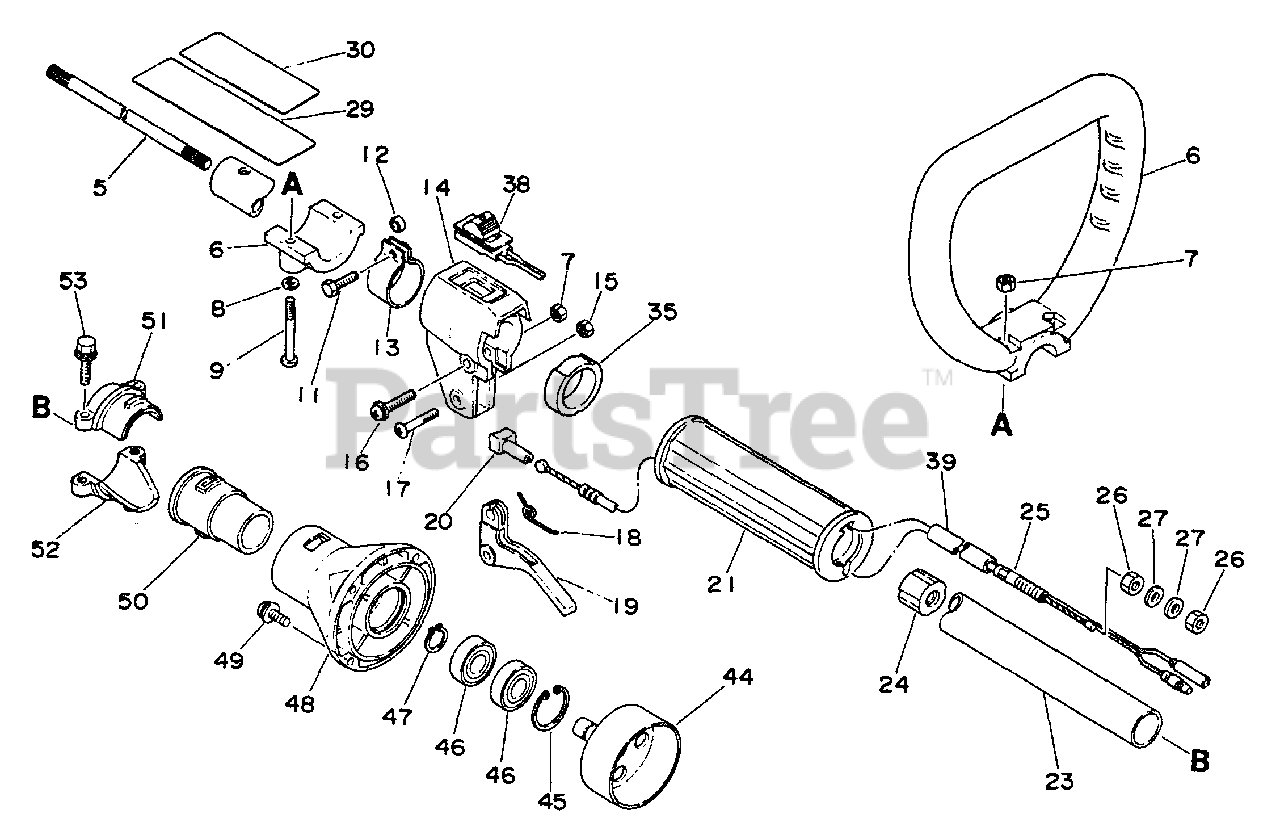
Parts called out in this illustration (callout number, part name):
5	DRIVESHAFT
6	LOOP HANDLE ASSY
8	WASHER - 5
9	SCREW - 5X40
11	BOLT - 5X18
14	BRACKET, THROTTLE CONTROL
15	LOCKNUT - 5
16	SCREW - 5X30
17	SCREW - 5X30
18	SPRING, TRIGGER
19	TRIGGER, THROTTLE
20	GUIDE, CABLE
21	GRIP, HANDLE
23	PIPE, MAIN
24	STOPPER
25	CABLE, THROTTLE
27	WASHER - 6
29	LABEL - CAUTION
30	LABEL - CAUTION
38	IGNITION SWITCH ASSY
39	TUBE - VINYL
44	DRUM, CLUTCH
45	RING, RETAINING - 28
46	BEARING, BALL - 6001
47	RING, RETAINING - 12
48	CASE, CLUTCH - ORANGE
49	SCREW - 5X16
51	CLAMP, MAIN PIPE - UPPER
52	CLAMP, MAIN PIPE
53	BOLT - 5X25
